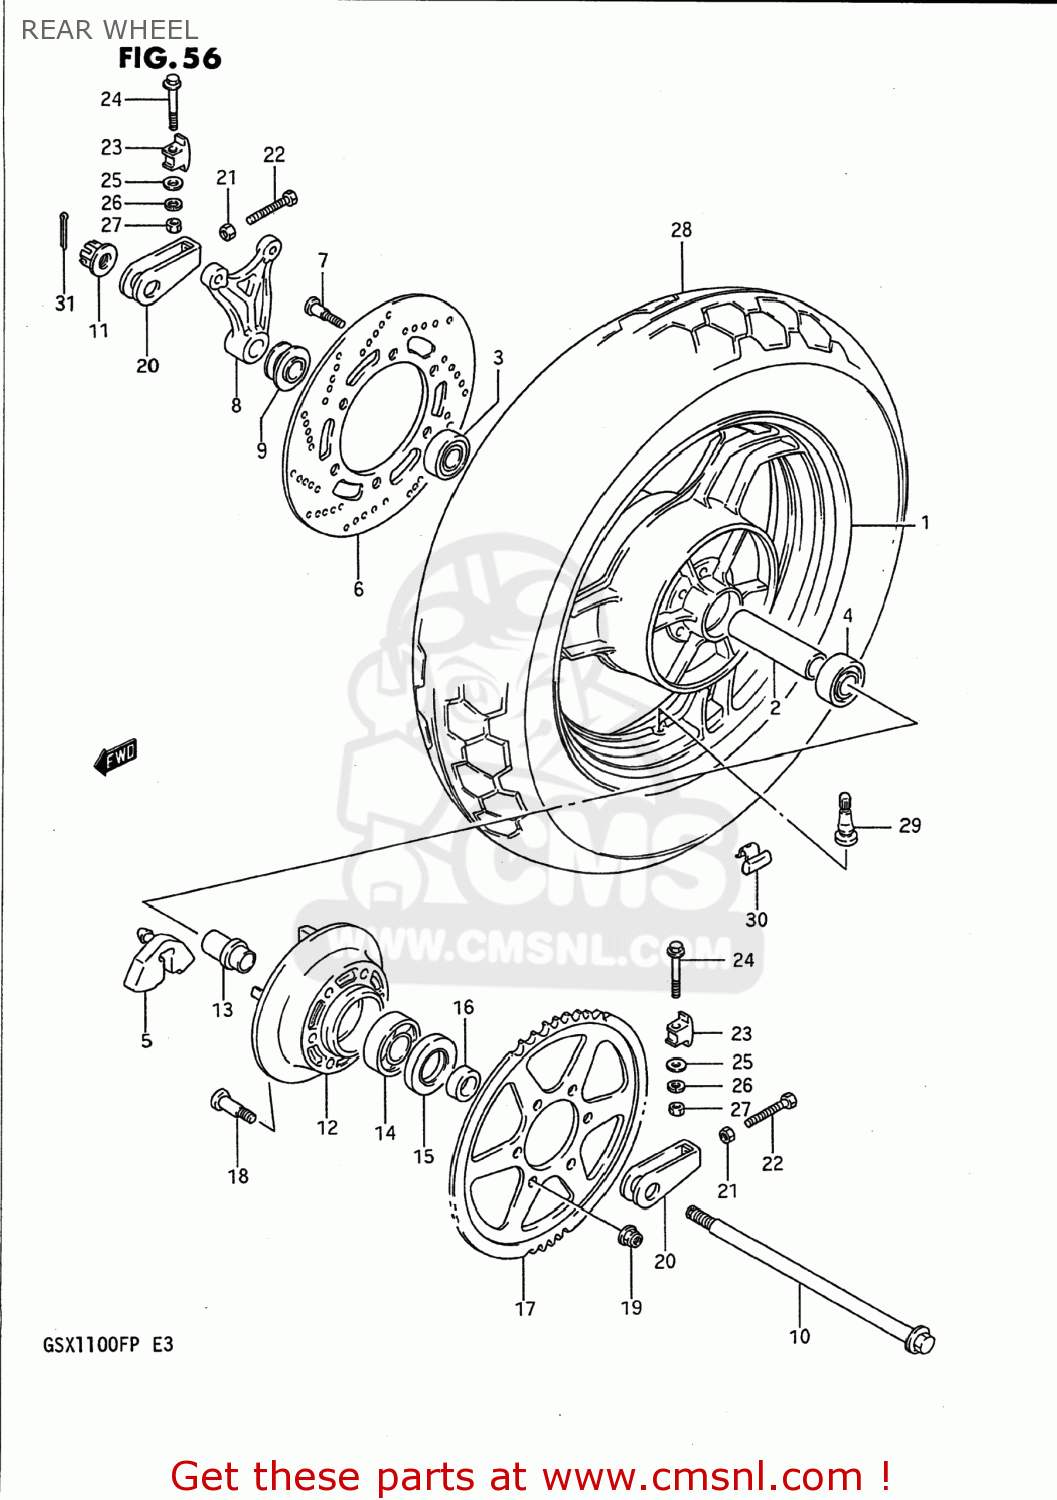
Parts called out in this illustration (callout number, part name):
1	WHEEL,RR(MT,3.50X16)
2	SPACER,REAR WHEEL HUB
3	BEARING
4	BEARING(20X47X14)
5	ABSORBER,RR HUB SHOCK
6	DISC,RR BRAKE
7	BOLT
8	BRACKET,RR,CALIPER
9	SPACER,RR AXLE,R
10	AXLE,RR
11	NUT
12	DRUM,RR SPROCKET MOUNTING
13	RETAINER,RR HUB BEARING
14	BEARING(25X62X17)
15	SEAL,OIL(35X62X8)
16	SPACER,REAR AXLE,LEFT
17	SPROCKET,RR(NT:52)
18	BOLT
19	NUT
20	ADJUSTER,CHAIN
21	NUT
22	BOLT
23	SUPPORTER,CHAIN ADJUST
24	BOLT 8X55
25	WASHER
26	WASHER,LOCK
27	NUT
28	TIRE
29	VALVE,TIRE
30	BALANCER,WHEEL
31	PIN,COTTER
